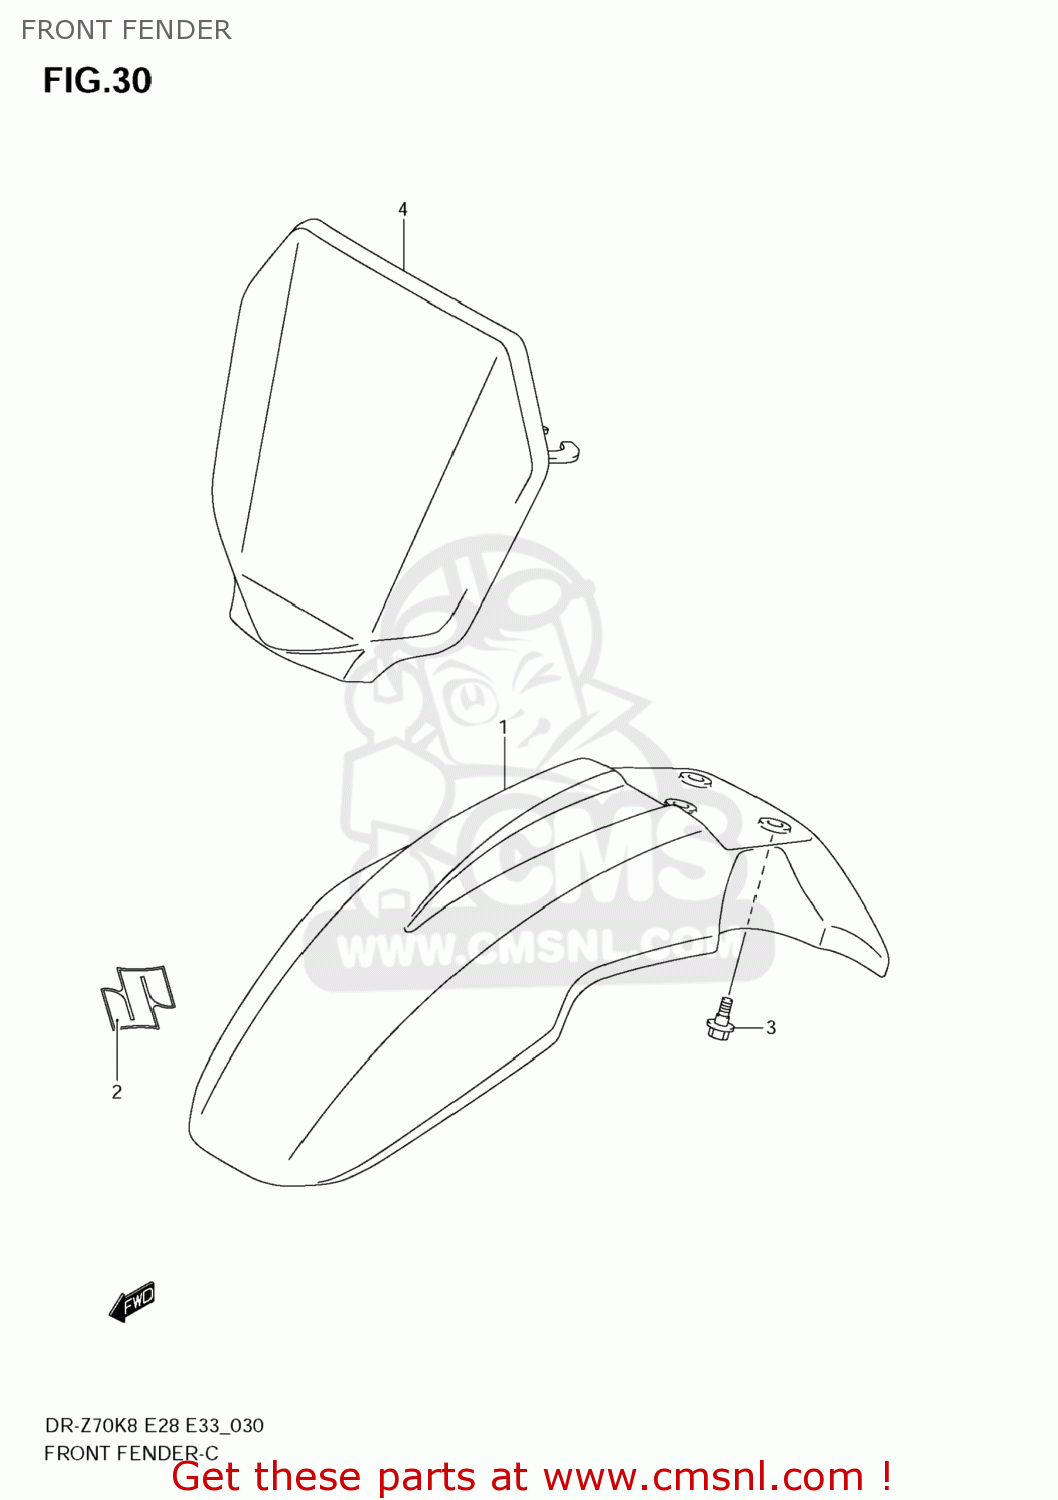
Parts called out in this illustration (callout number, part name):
1	FENDER,FR
2	EMBLEM,S
3	BOLT(6X17.8)
4	PLATE,NUMBER FR
